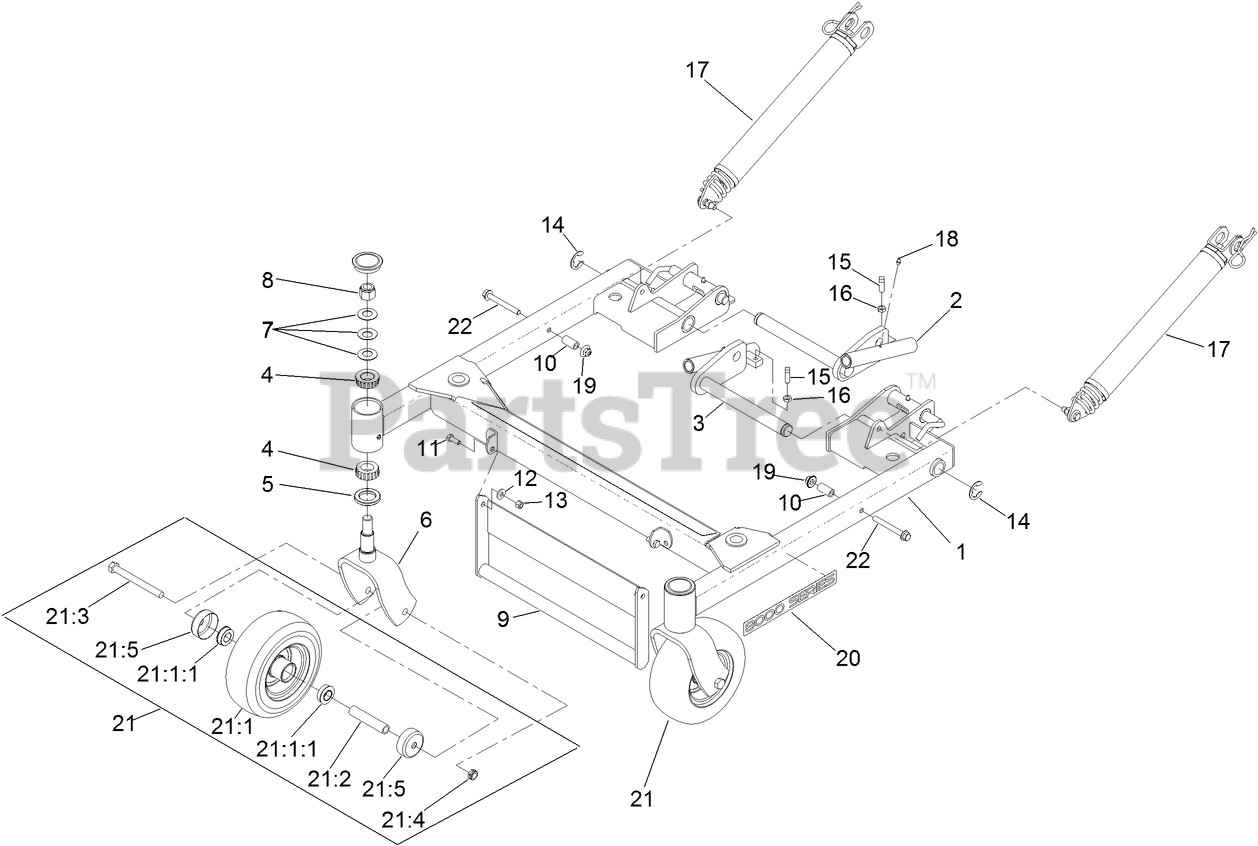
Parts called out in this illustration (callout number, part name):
1	FRAME-DECK SUPPORT W/DECALS
2	PIVOT-DECK, RH
3	PIVOT-DECK, LH
4	BEARING-ROLLER, TAPERED
5	SEAL-GREASE
6	FORK-CASTER
7	WASHER-BELLVILLE
8	NUT-LOCK, NI
9	HANDLE-LIFT
10	SPACER
11	SCREW-HH
12	WASHER-SPRING
13	NUT-LOCK, NI
14	RING-SNAP
15	SCREW-SET, SQH
16	NUT-JAM
17	LIFT ASSIST SPRING ASM
18	FITTING-GREASE
19	NUT-FLANGE, NI
21	WHEEL AND AXLE ASM
21:1	WHEEL AND TIRE ASM
21:1:1	BEARING-BALL
21:2	SPACER-CASTER, FRONT
21:3	SCREW-HH
21:4	NUT-HEX
21:5	GUARD-SEAL
22	SCREW-HHF
